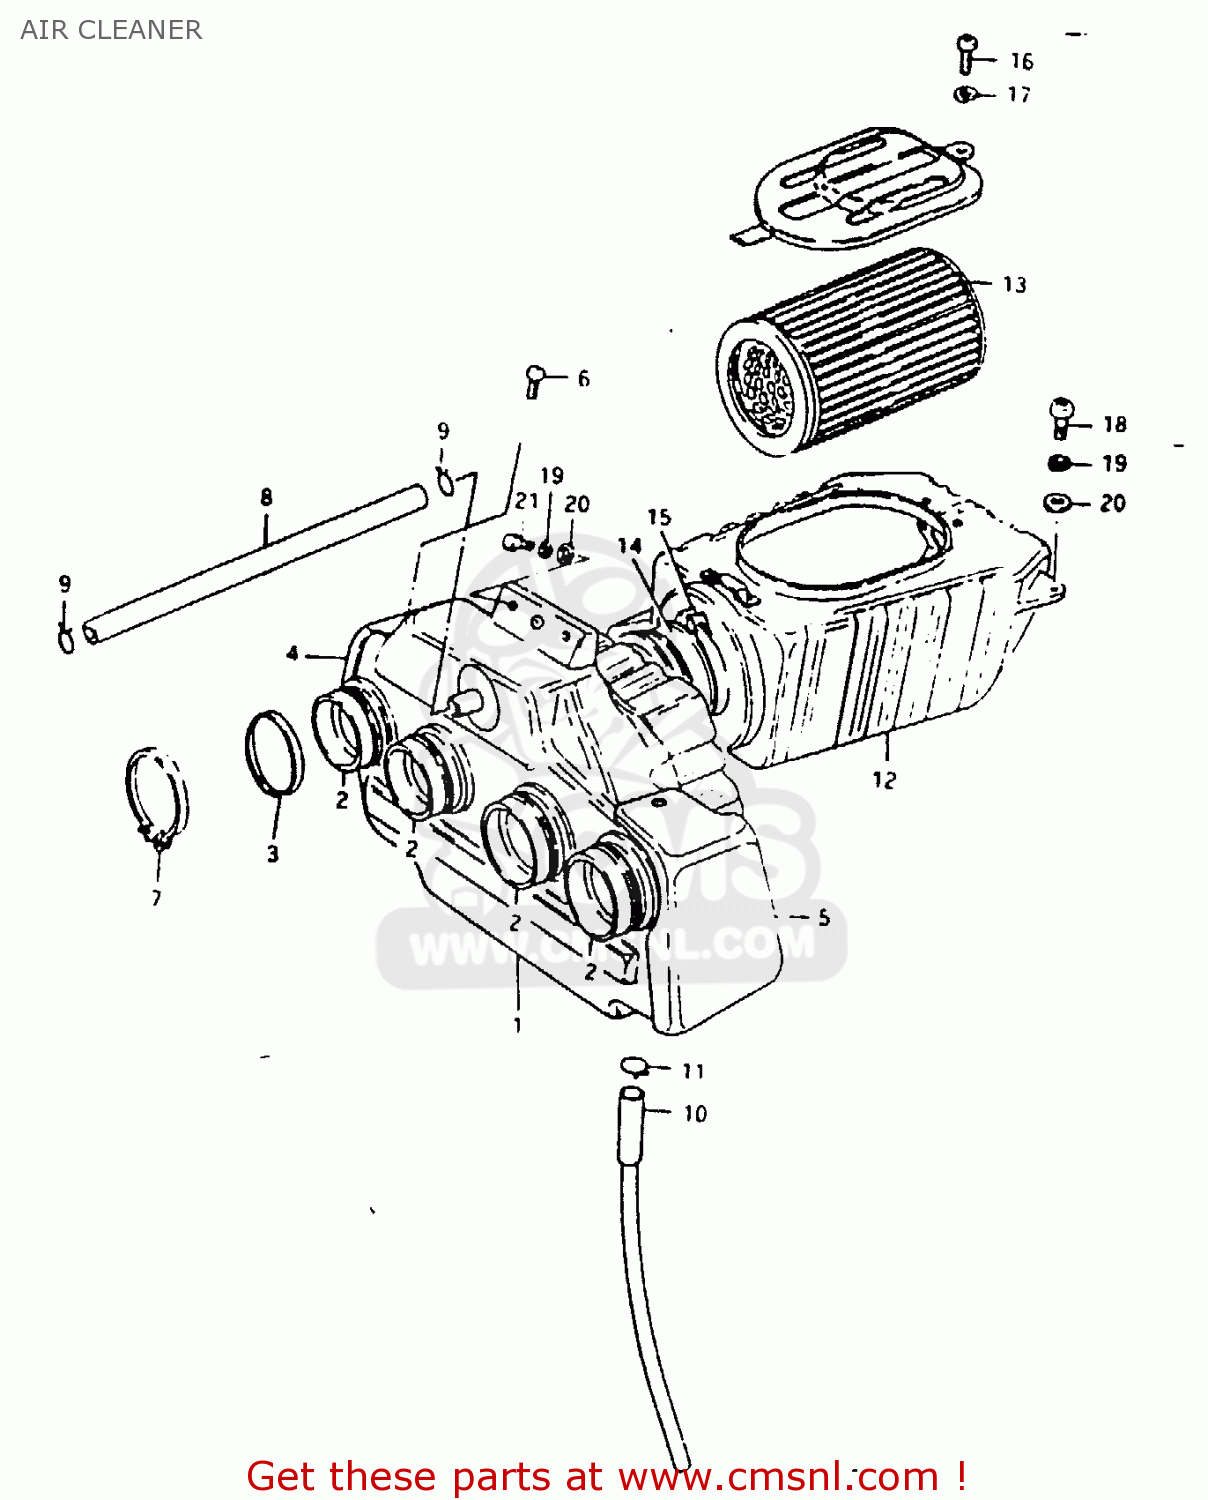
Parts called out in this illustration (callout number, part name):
1	CASE ASSY, FRONT
2	TUBE,AIR CLEANER OUTLET
3	RING,CARBURETOR AIR INLET HOSE
4	COVER,AIR CLEA
5	COVER
6	SCREW 4X10
7	CLAMP
8	TUBE,BREATHER
9	CLIP
10	DRAIN TUBE
11	CLIP
12	CASE SET, REAR
13	FILTER ASSY
14	HOSE,AIR CLEANER
15	BAND
16	SCREW
17	LOCK WASHER
18	SCREW
19	LOCK WASHER
20	WASHER
21	BOLT
